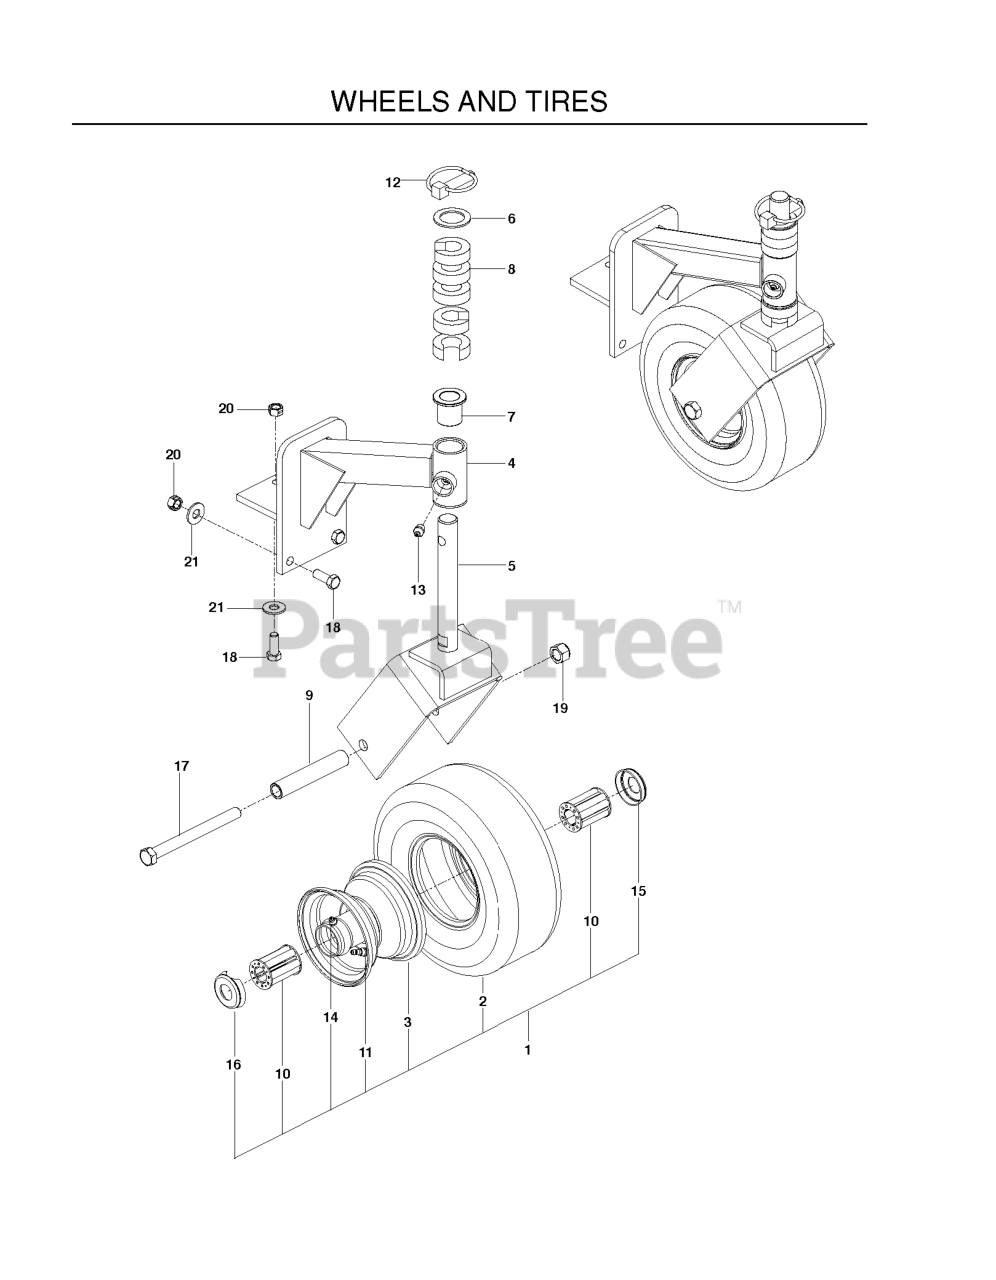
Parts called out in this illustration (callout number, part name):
1	TIRE/WHEEL.CASTER.9X3.5-4.SMOO
2	TIRE 9 X 3.5 - 4
4	CASTER ARM W/BUSHING
5	CASTER YOKE
6	MACHINE BUSHING
7	BUSHING, FLANGED
10	ROLLER BEARING
11	VALVE STEM TR-412
12	LYNCH PIN 7/16
13	ZERK 1/8 NPT
14	GREASE ZERK
15	ENDCAP
16	ENDCAP, NOTCHED
17	HCS 1/2C X 5 1/2
18	HCS 3/8-16X1.GRD.5.ZD
19	NUT 1/2-13 HEX NYLOC ZD
20	NUT 3/8C CENTERBLOCK
21	WASHER 3/8 FLAT
